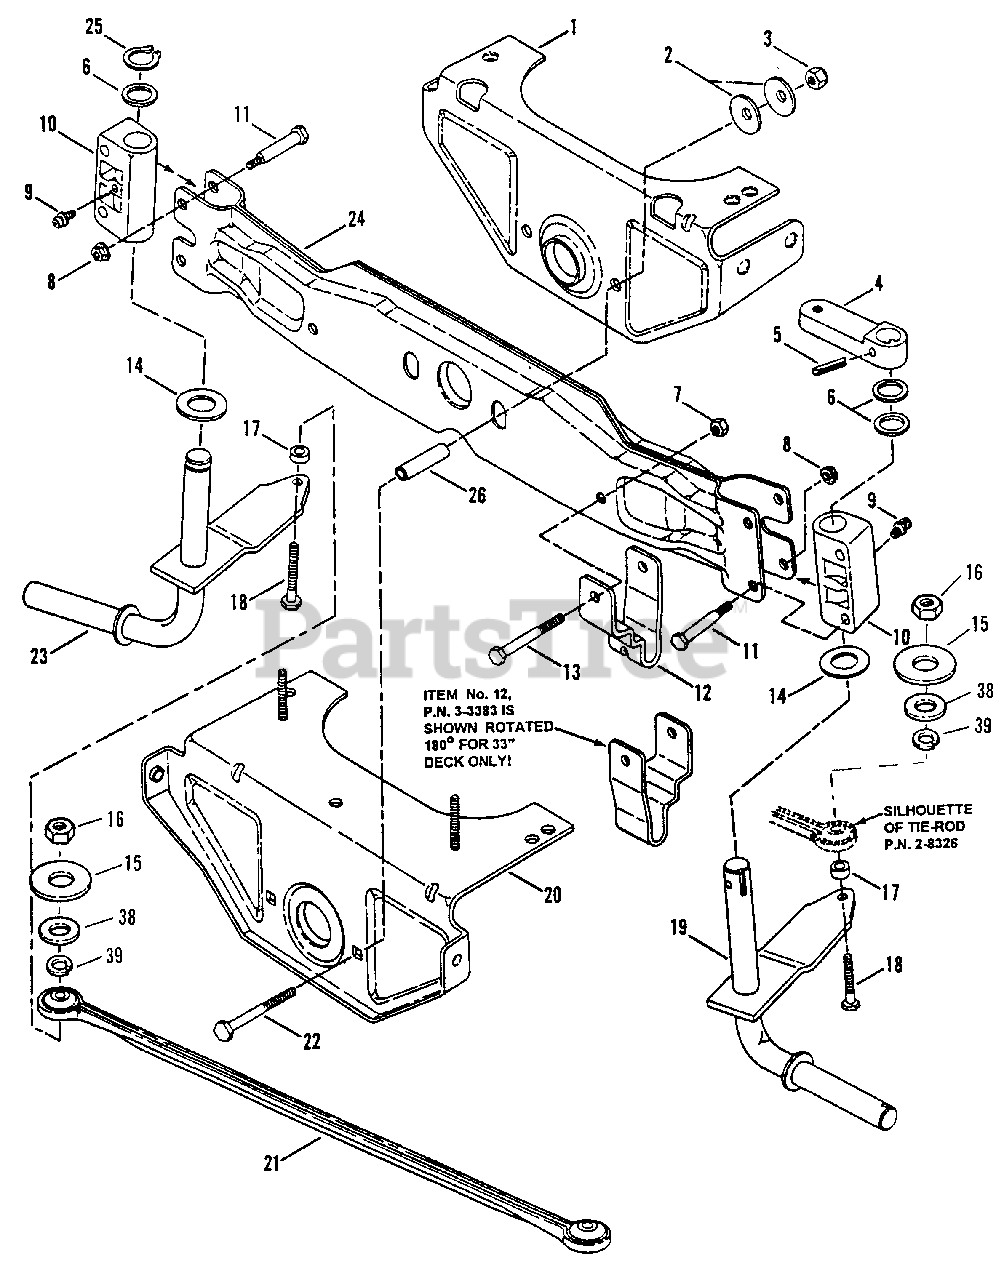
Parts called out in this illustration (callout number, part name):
1	BRACKET, Axle (Rear)
2	WASHER, Cone
3	NUT, 3/8-16 Nyloc
4	ARM, Steering
5	ROLL-PIN, 1/4 x 1-1/4"
6	WASHER, Shim
7	NUT, 5/16-18 Center Lock, Gr. 5
8	NUT, 1/4-20 Hex Flange Top-Lock, Grade B
9	LUBE FITTING, Straight (press-fit for .187 dia. Hole)
10	BEARING, Spindle
11	BOLT, 1/4-20 x 1-1/64" Shoulder
12	BRACKET, Deck Hanger
13	SCREW, 5/16-18 x 2 1/2" Hex Head Cap, Grade 5
14	WASHER, Thrust
15	WASHER, 13/32 x 1-3/8" Flat
16	NUT, 3/8-16 Hex Head Center Lock, Grade 5
17	SPACER, Tie-Rod
18	SCREW, 3/8-16 x 1-3/4" Hex Head Cap, Grade 5
19	SPINDLE ASSY., Left Hand, Long
19	SPINDLE ASSY., Left Hand, Short
20	BRACKET ASSEMBLY, Axle (Front)
21	TIE-ROD
22	BOLT, 3/8-16 x 3" Hex Hd, Gr.5
23	SPINDLE ASSY., Right Hand, Long
23	SPINDLE ASSY., Right Hand, Short
24	AXLE, Front
25	RING, Retaining
26	SPACER
38	WASHER, 3/8" Flat
39	WASHER, 3/8 x 11/16" Split Lock
